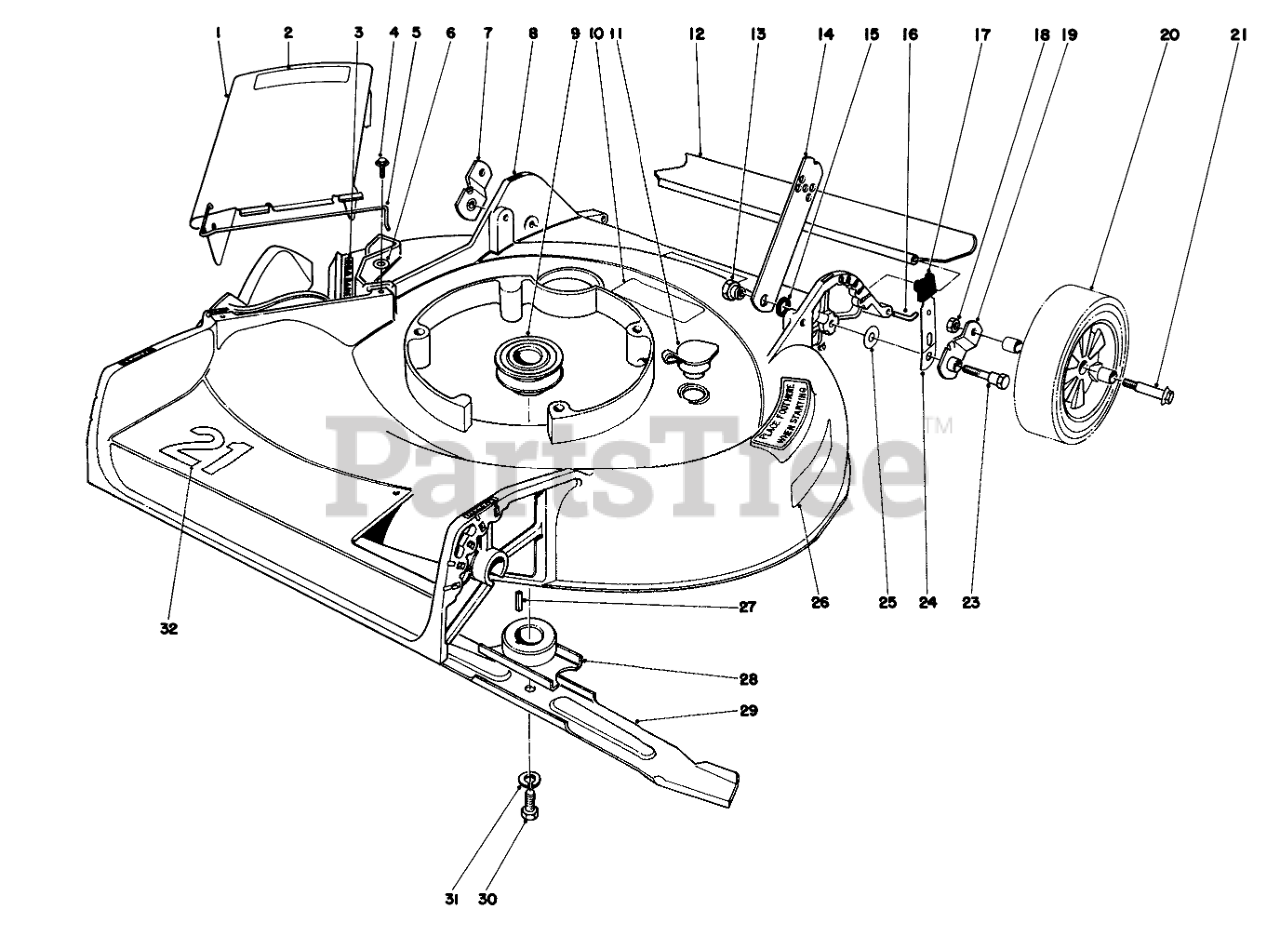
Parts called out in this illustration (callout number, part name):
1	Deflector Cover Assembly (Incl. Ref. #2 & 5)
2	Decal-Caution
3	Decal-Danger
4	SCREW
5	SPRING HINGE
6	WASHER-FLAT
7	Pivot Arm
8	Housing
9	DRIVER PULLEY
10	Decal-Warning
11	WASHOUT PLUG
12	REAR SAFETY SHIELD 21
13	HANDLE PIVOT NUT
14	HANDLE LATCH
15	HANDLE LATCH SPACER
16	SHIELD ROD
17	KNOB-ARM
18	Nut
19	Pivot Arm
20	WHEEL TIRE ASM 8 IN
21	BOLT-WHEEL
23	PIVOT SCREW
24	SPRING ARM ASM
25	WASHER-PIVOT
26	Decal-Step
27	KEY-SQUARE
28	Blade Retailer
29	Blade
30	SPECIAL SCREW
31	WASHER-LOCK
32	Decal 21"
